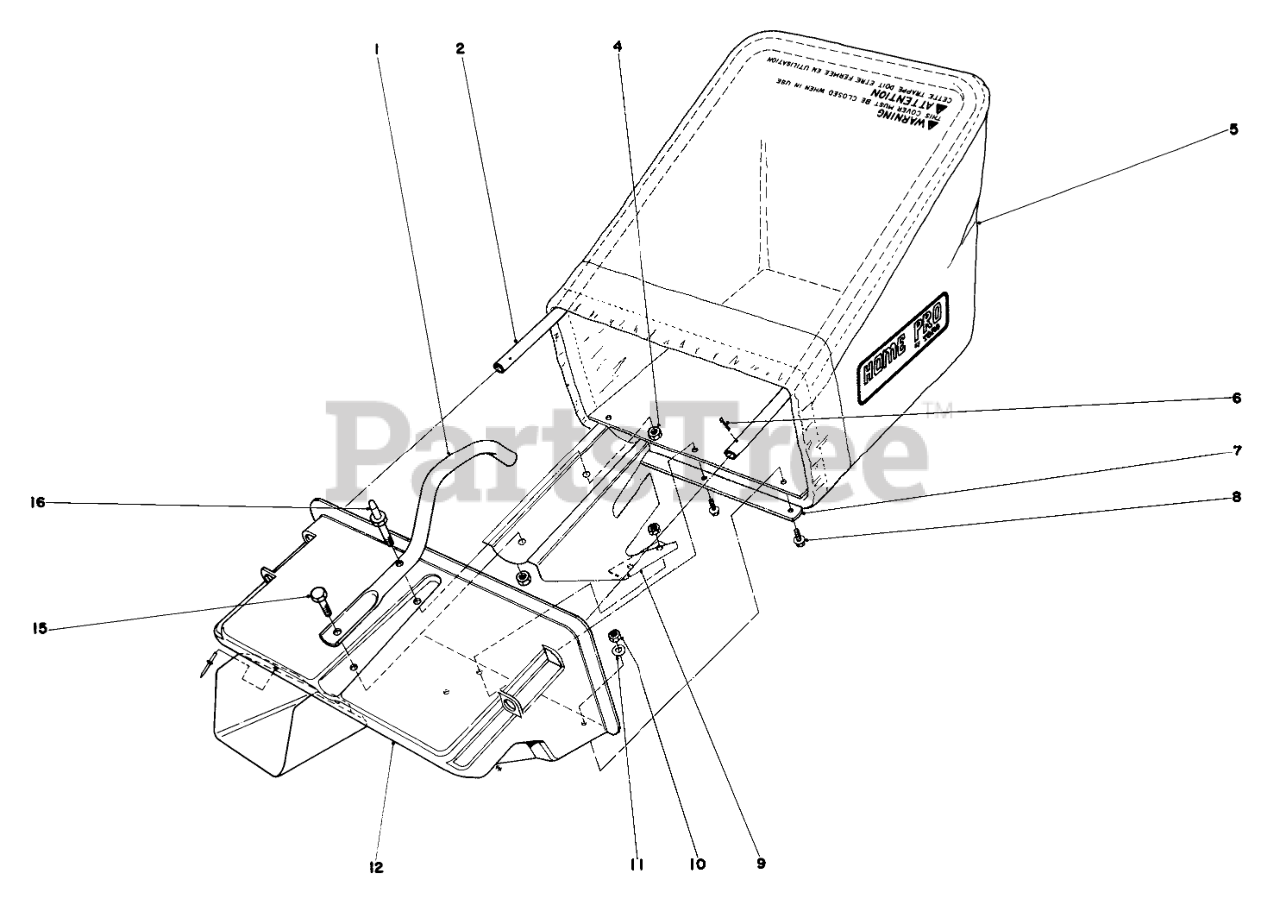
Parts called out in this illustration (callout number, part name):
1	BAG HANDLE
2	BAG FRAME
4	Nut
5	Grass Bag
6	PIN-COTTER
7	BAG RETAINER
8	SCREW-HWH
9	BAFFLE-BAG SHELL
10	Nut
11	WASHER-FLAT
12	Bag Shell
15	SCREW-HH
16	HANDLE STUD
